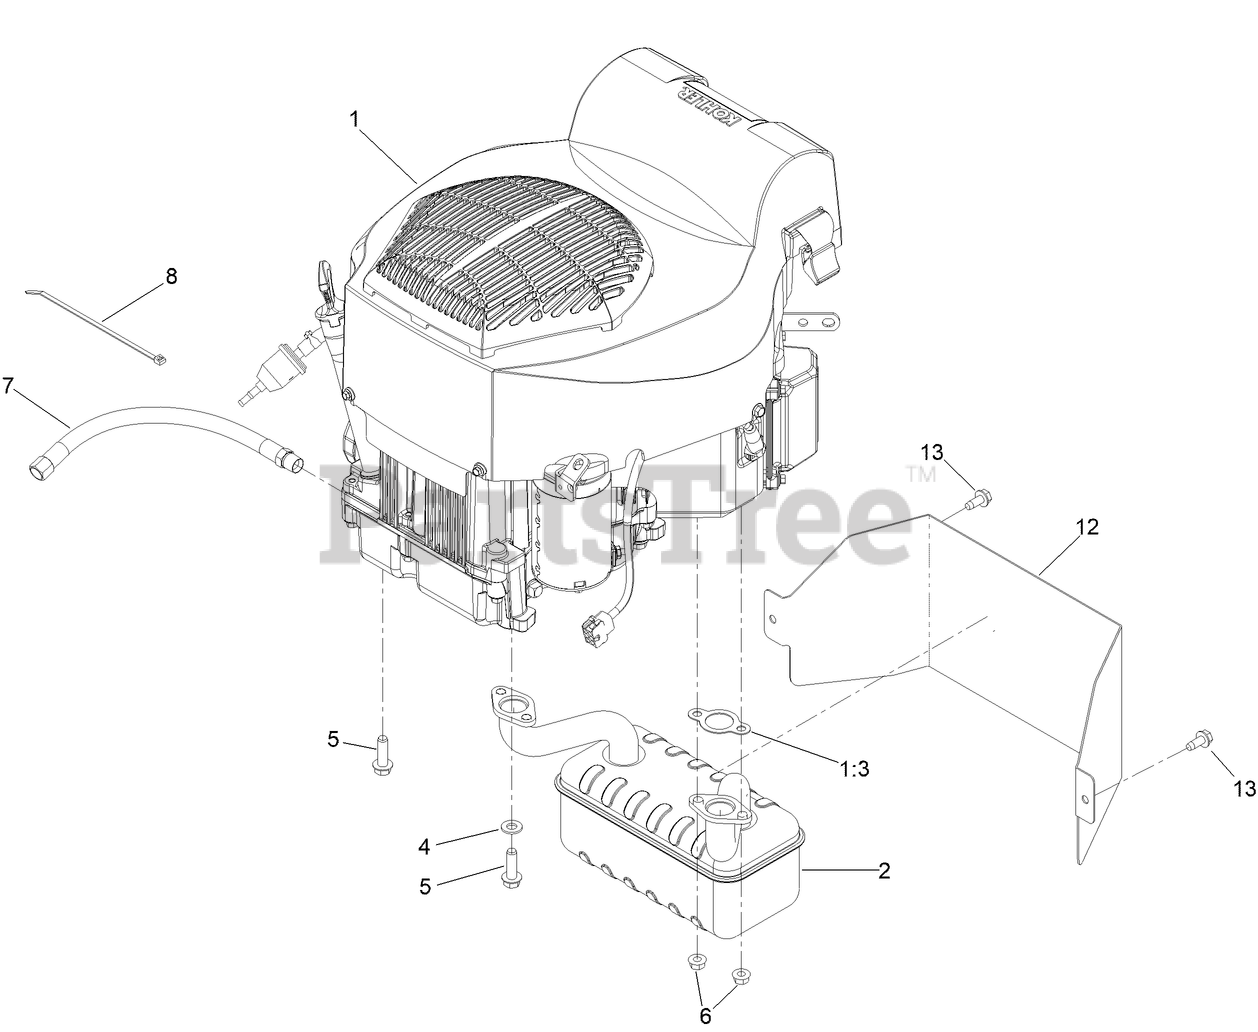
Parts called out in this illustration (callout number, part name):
1:3	GASKET-EXHAUST
2	MUFFLER
4	WASHER-FLAT
5	SCREW-THD
6	NUT-HF
7	HOSE-DRAIN, OIL
8	TIE-CABLE
12	HEAT SHIELD - MUFFLER
13	SCREW-HWHTF
